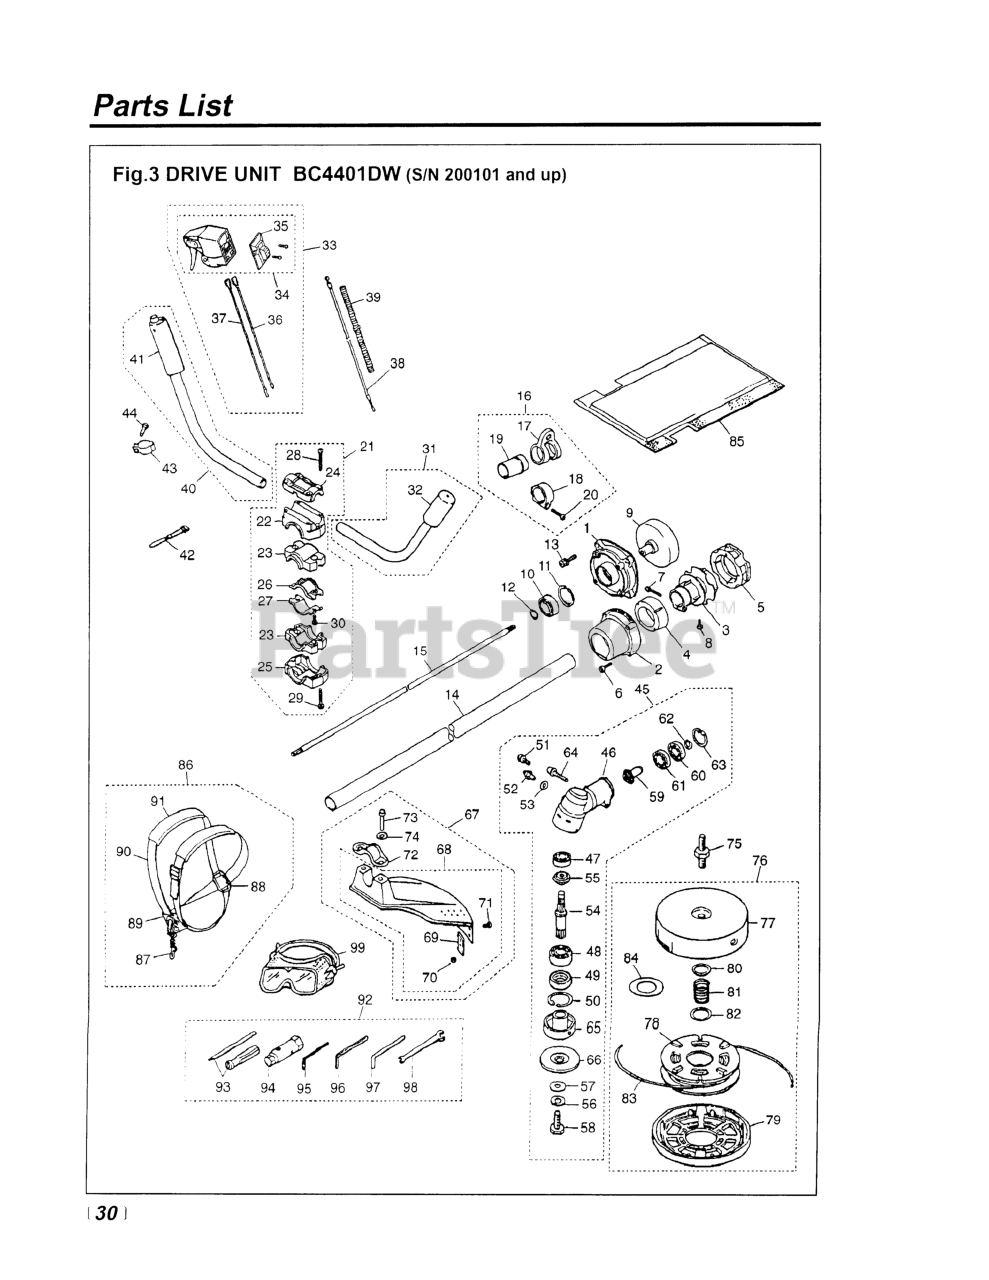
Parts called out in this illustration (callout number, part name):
1	HOUSING
2	CAP
3	JOINT
4	ABSORBER-F
5	ABSORBER-R
6	BOLT, M5 X 30
7	BOLT, M6 x 30
8	BOLT, M5 X 10
10	BEARING
11	RING, SNAP, M35 X 1.5
12	RING, SNAP, M15 X 1.0
13	BOLT, M6 x 20
14	PIPE COMPLETE
15	SHAFT (REPLACES -12211)
16	HANGER ASSEMBLY
17	HANGER
18	CLAMP
20	SCREW, M5 x 25
21	BRACKET ASSY.
22	BRACKET (RPLS -14110)
23	ABSORBER
24	CAP, UPPER (RPLS -14191)
25	CAP, LOWER (RPLS -14120)
26	CLAMP (A)
27	CLAMP (B)
28	BOLT, M5 X 25
29	BOLT, M5 X 35
30	BOLT (USE 3310-31720)
31	HANDLE COMPL, LEFT
33	LEVER COMP.
34	LEVER ASSEMBLY
35	0 6234-14601-02
36	CORD (A), BLACK
37	CORD (B), RED
39	TUBE
40	HANDLE COMPL, RIGHT
41	GRIP
42	BAND
43	CLAMP
44	SCREW, M5 X 16
45	GEAR CASE ASSY.
46	GEARCASE
47	BEARING (RPLS T3403-13510)
49	SEAL, OIL
50	RING, SNAP, M32 x 1.2
51	BOLT, M5 X 10
52	FITTING, GREASE
53	WASHER, M6 X .8
54	SHAFT
55	GEAR, BEVEL
56	WASHER (RPLS 3180-13270)
57	WASHER, M8 x 2.3 (RPLS -20823)
58	BOLT, LH
59	PINION
61	BEARING (RPLS T3403-13510)
62	RING, SNAP
63	RING, SNAP, M26 X 1.2
64	BOLT, M6 x 1.35
65	HOLDER (A)
66	HOLDER (B)
67	GUARD ASSEMBLY
68	GUARD COMP.
69	BLADE
70	NUT
71	SCREW, M5 x 12
72	CLAMP
73	BOLT, M6 x 1.30
74	WASHER, M6 X 15
75	SHAFT (RPLS 3274-99120)
76	6
77	CASE (RPLS. -99111)
78	CORD HOLDER (RPLS. -99140)
79	COVER
80	PLATE, LARGE
81	SPRING (RPLS -99161)
82	PLATE, SMALL
83	CORD
84	SPACER
85	PROTECTOR
86	HARNESS ASSY (RPLS -95200)
87	HOOK, HARNESS (RPLS -17210)
89	HANGER COMP.
90	BAND (NOT SOLD SEPARATELY)
91	PROTECTOR
92	TOOL SET
93	SCREWDRIVER
95	WRENCH (TOOL)
96	WRENCH (TOOL)
97	BAR
98	SPANNER, 8 X 10 (RPLS 2540- )
